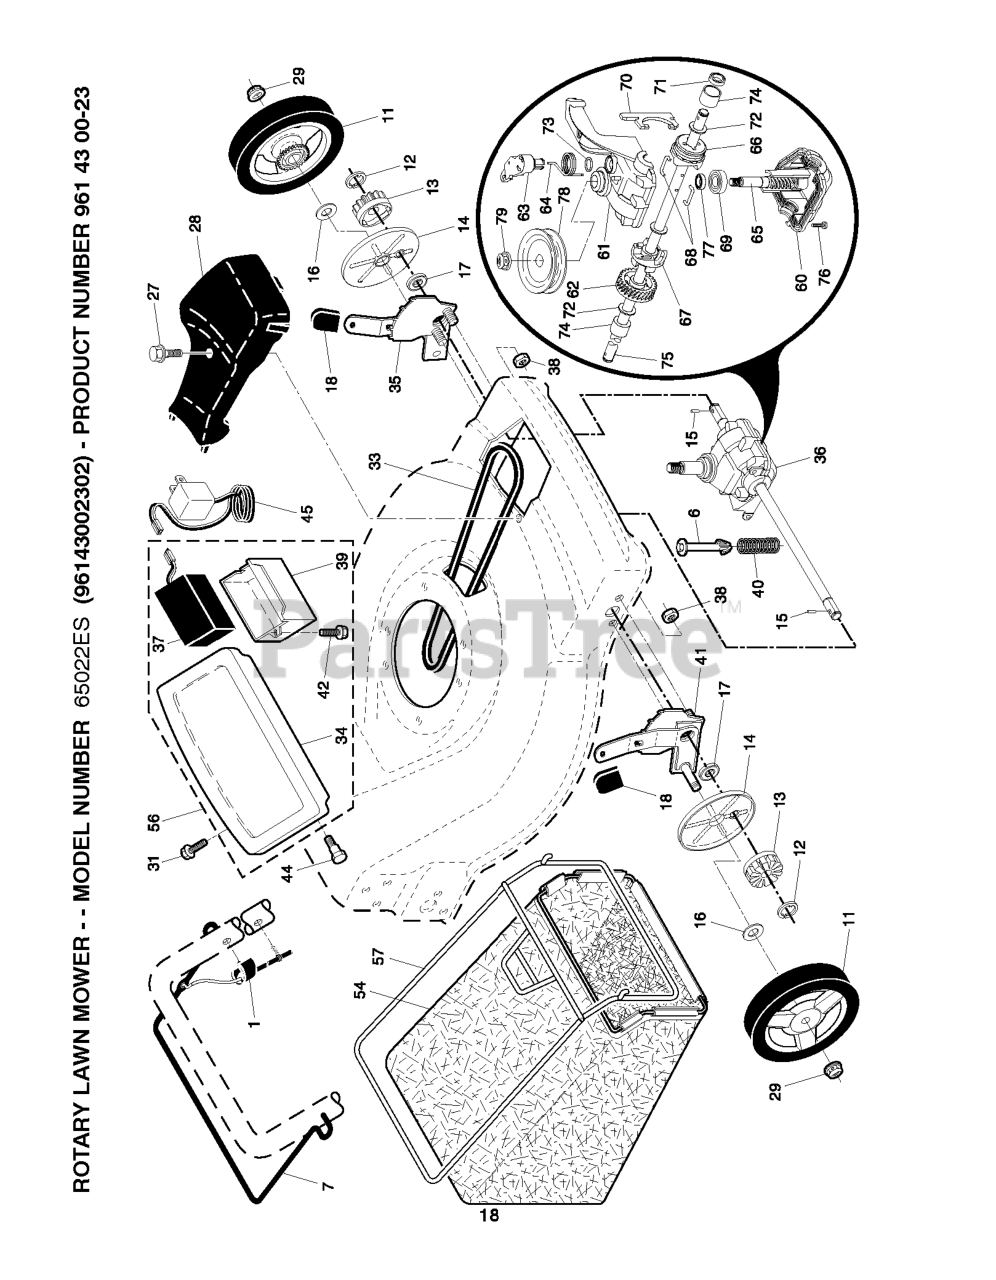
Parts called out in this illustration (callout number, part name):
1	CONTROL.DRIVE.S/SPEED.FWGD
6	SPRING RETAINER
7	BAIL.CONT.DR.S/S.ROUND.ORG
11	WHEEL.8X1.75.H3SPK.RAD3.GY.BU3
12	E-RING 7/16 RE
13	PINION.14.TEETH.FGD
14	COVER.DUST.WHEEL
15	PAWL, DRIVE
16	WASHER FLUT
17	BEARING
18	KNOB.DELUXE.GRAY
27	SCREW, HEX HD TAPPING #10-24 1
29	NUT.HEX.FLANGE.3/8-16.LO(3 2)
31	SCREW.PAN.HEAD.#10
33	BELT THERM .32
34	PANEL.TRIM.21.FWGD.ES
35	WHEEL ADJ KIT LH
36	TRANSMISSION.22.FGD/W/PULLEY
37	BATTERY WITH AMP CONECTOR AGM
38	LOCKNUT.NYLOC.1/4-20
39	BOX.BATTERY.TRIM
40	SPRING.EXTENSION
41	WHEEL ADJ KIT RH
42	SCREW.HWH.13-16X.50
44	SCREW.SHOULDER.HH.10X.281X.6
45	RP CHARGER.BATTERY
54	GBAG.8471024T.SIL.HUSQ.BLU
56	PANEL.ASM.TRIM/BATTERY.BOX
57	FRAME.GBAG.22.EZ.EMPTY.SC
60	LOWER CASE
61	UPPER CASE
62	GEAR.27.TEETH.WALK.MOWER
63	LEVER, CLUTCH
64	SPRING, RETURN
65	SHAFT.INPUT.WORM.GEAR(13155)
66	DOG, MOVABLE (11032)
67	DOG, FIXED GT11031
68	WIRE, FORMED (15966)
70	FORK, SHIFT
71	SEAL.OUTPUT.SHAFT
73	SEAL, CASE O-RING
75	SHAFT OUTPUT (12260 NOW 12663)
77	SEAL INPUT SHAFT
